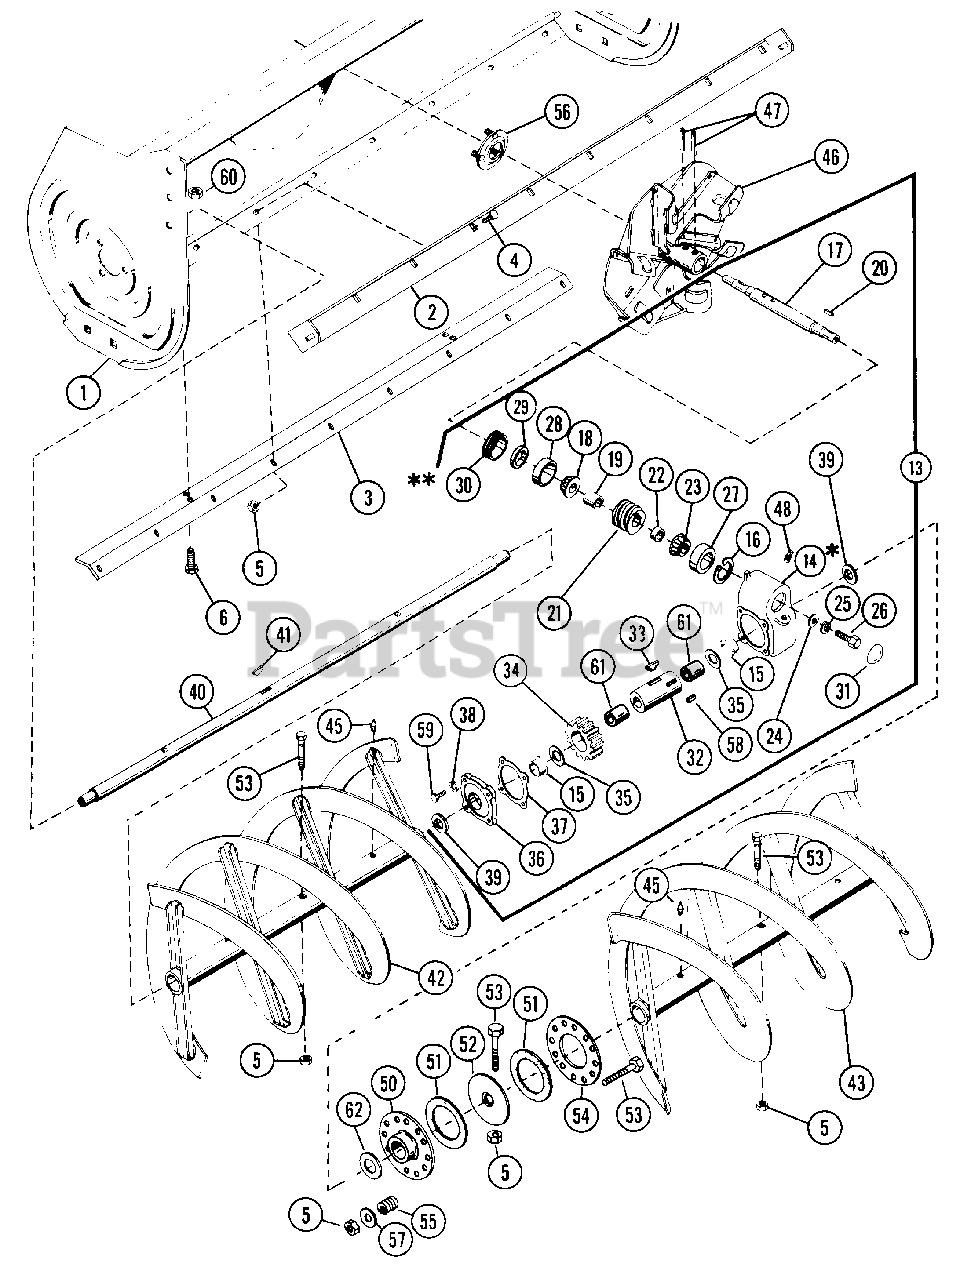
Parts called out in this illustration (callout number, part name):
1	48-INCH SNO THRO HOUSING
2	SCRAPER BLADE
3	SCRAPER BLADE BRACE
4	BOLT, CARRIAGE 5/16-18X.75
5	NUT, LOCK 5/16-18
6	BOLT, HEX 3/8-16X.75
13	BLOWER GEARCASE
14	GEAR CASE
15	BUSHING, FLANGE 1.62X1.87X11
16	RING, SNAP INTERNAL 1.781
17	SHAFT, WORM
18	BEARING CONE
19	BEARING SPACER
20	KEY, STRAIGHT SAE 1035
21	WORM
22	SPACER, BEARING
23	BEARING CONE
24	WASHER, FLAT .344X.688X.065
25	WASHER, LOCK 3/8 SP HEAVY
26	BOLT, HEX 5/16-18X.75
27	BEARING CUP
28	BEARING CUP
29	SEAL
30	ADJUSTMENT PLUG
31	CAP, DUST
32	GEARCASE SHAFT
33	KEY, FEATHER
34	GEAR, WORM
35	WASHER, 1.625X2.50X.012
36	COVER, GEAR CASE
37	GASKET
38	WASHER, LOCK 1/4 EXT TH TYA
39	SEAL
40	48" RAKE SHAFT
42	RIGHT RAKE
43	LEFT RAKE
45	FITTING, LUBE 1/4-28
46	FAN
47	PIN, ROLL 5/16X1.75
48	PIPE PLUG
50	DRIVER
51	FRICTION DISC
52	DRIVER PLATE
53	BOLT, HEX 5/16-18X2.00
54	PRESSURE PLATE
55	SPRING, COMPRESSION
56	BEARING, FLANGE
57	WASHER, FLAT
58	KEY, STRAIGHT
59	BOLT, HEX 1/4-20X.875
60	NUT, LOCK 3/8-16
61	BUSHING, SLEEVE
62	WASHER
